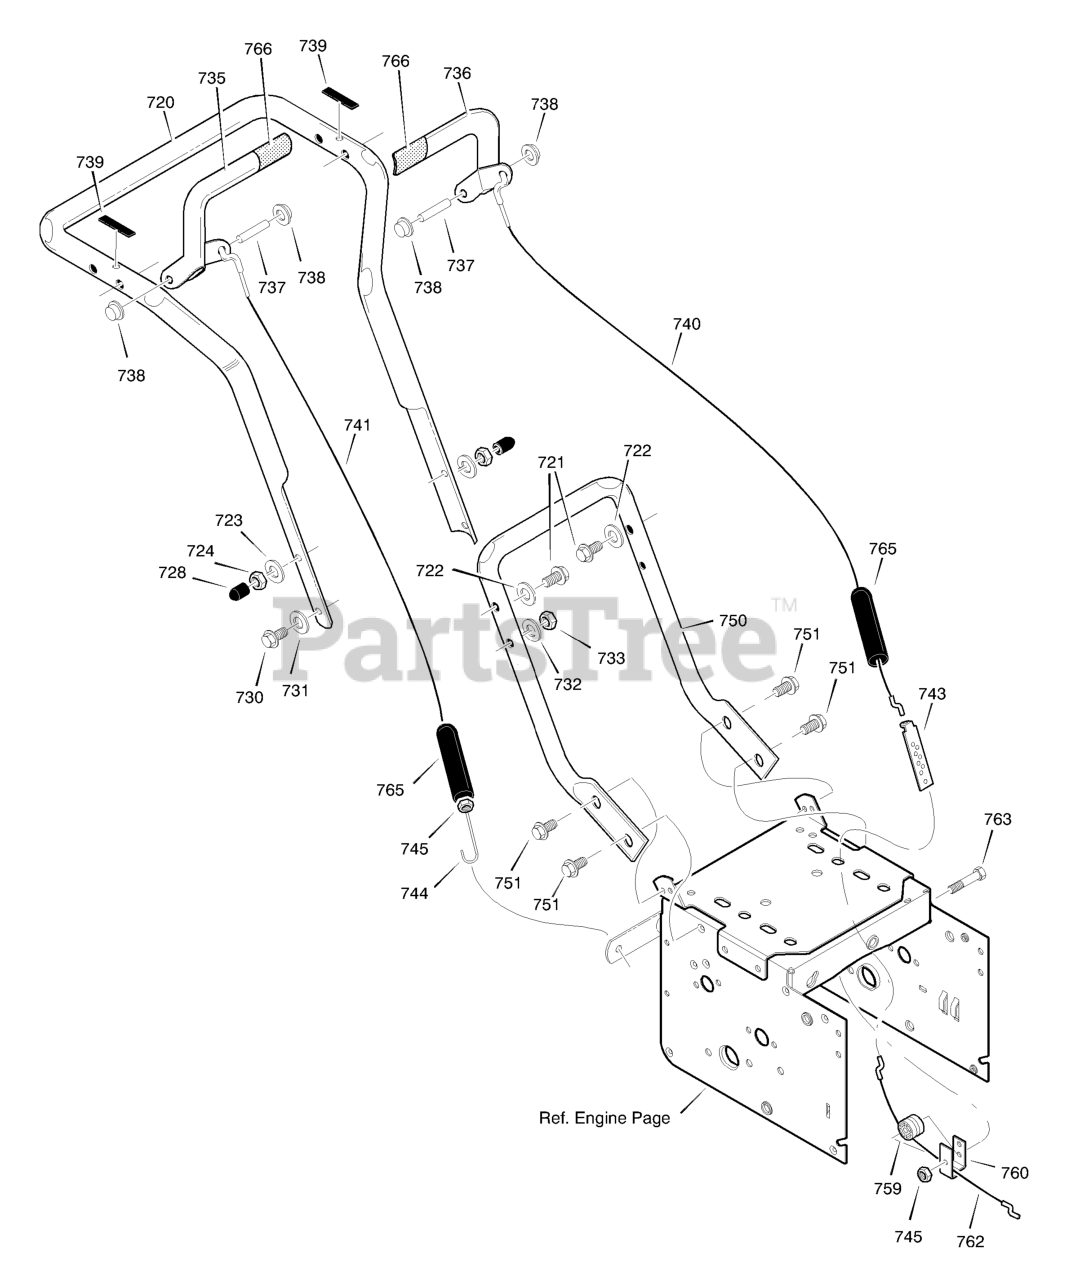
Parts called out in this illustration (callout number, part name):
720	HANDLE, UPPER
721	SCREW, 3/8-16 x 3.00
722	WASHER, FLAT
723	WASHER
724	NUT, 3/8-16
728	STOP, PLASTIC
730	SCREW, 3/8-16 X 2
731	WASHER, FLAT
732	WASHER
733	NUT, 3/8-16
735	HANDLE, RIGHT
736	HANDLE, LEFT
737	PIN, PIVOT CLUTCH
738	NUT, PUSH ON CAP
739	BUMPER, RECTANGLE
740	CABLE, DRIVE
741	CABLE, AUGER CLUTCH
743	BRACKET, CABLE ADJUSTER
744	SPRING, AUGER CLUTCH
745	NUT, 1/4-20
750	HANDLE, LOWER
751	SCREW, TAP 5/16-18 X .75
759	SPOOL-CABLE, AUGRT CLUTCH
760	BRACKET, CABLE SPOOL YZ
762	CABLE, LOWER DRIVE 12"
763	BOLT, HEX 1/4-20 X 1.5
765	BOOT, CLUTCH SPRING
